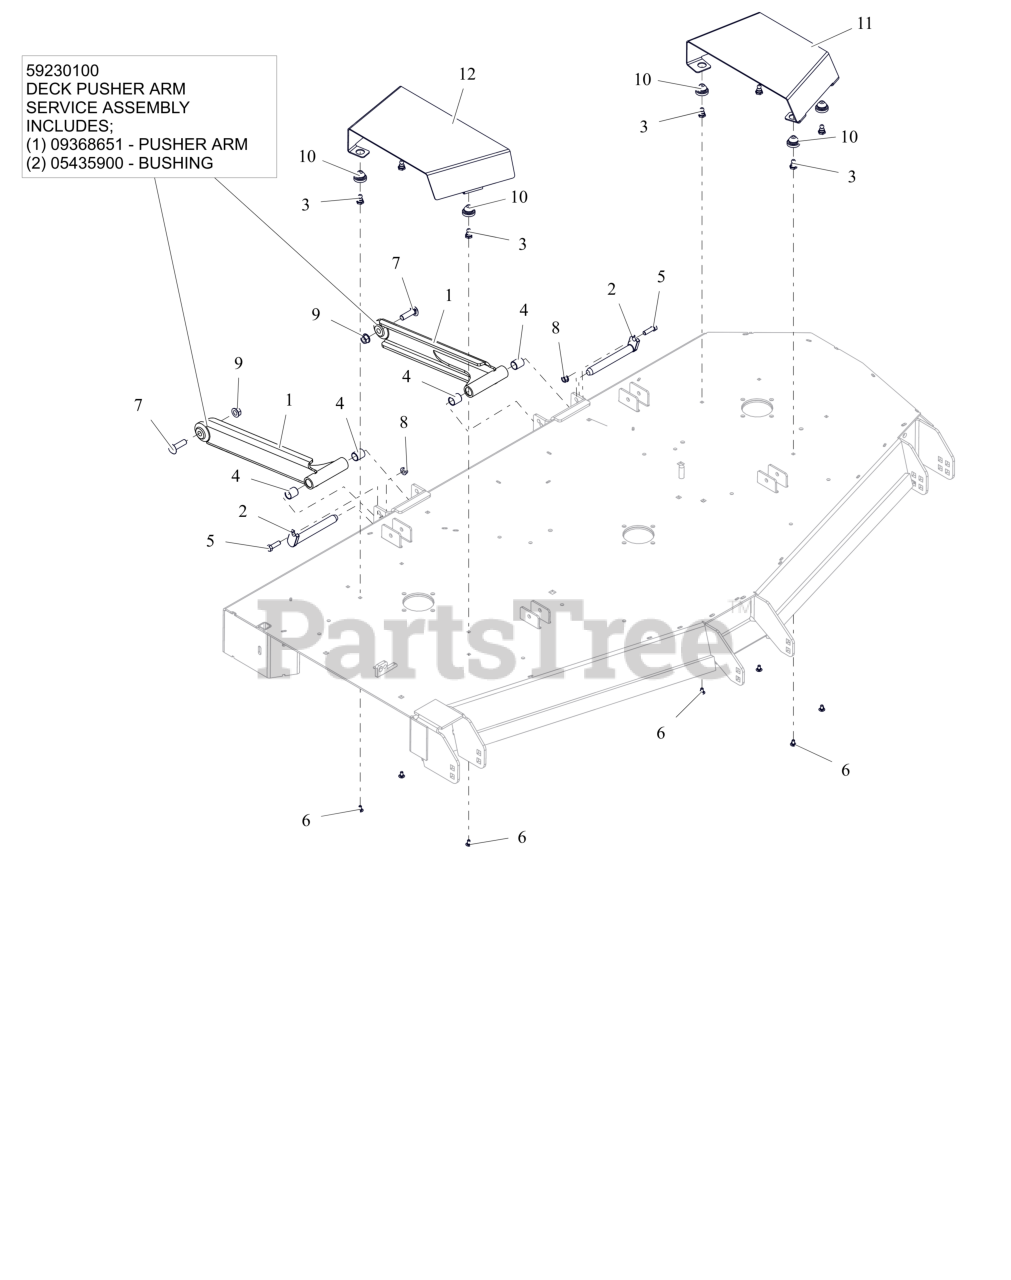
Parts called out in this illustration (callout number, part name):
1	WLDMT, DECK STABILIZER ARM (BLACK)
1	DECK PUSHER ARM SERVICE ASSEMBLY
1	BRG, .750 X .875 X 1.000
2	PIN, MOWER MTG
3	STUD, BALL FEMALE .250-20 THREAD
4	BRG, .750 X .875 X 1.000
5	BLT, HEX .38-16X1.25 G5 ZCC
6	BLT, RHSSN.25-20X.500 G5 ZCC
7	BTL,RHSSN .500-13 X 1.75 G5 ZCC
8	NUT-LK-CTR-FLG .375-16 GF ZCC
9	NUT-LK-CTR-FLG .500-13 GG ZCC
10	COUPLING, RUBBER PUSH-IN
11	GUARD, LH DECK BELT 72" (RED)
12	GUARD, RH DECK BELT 72" (RED)
